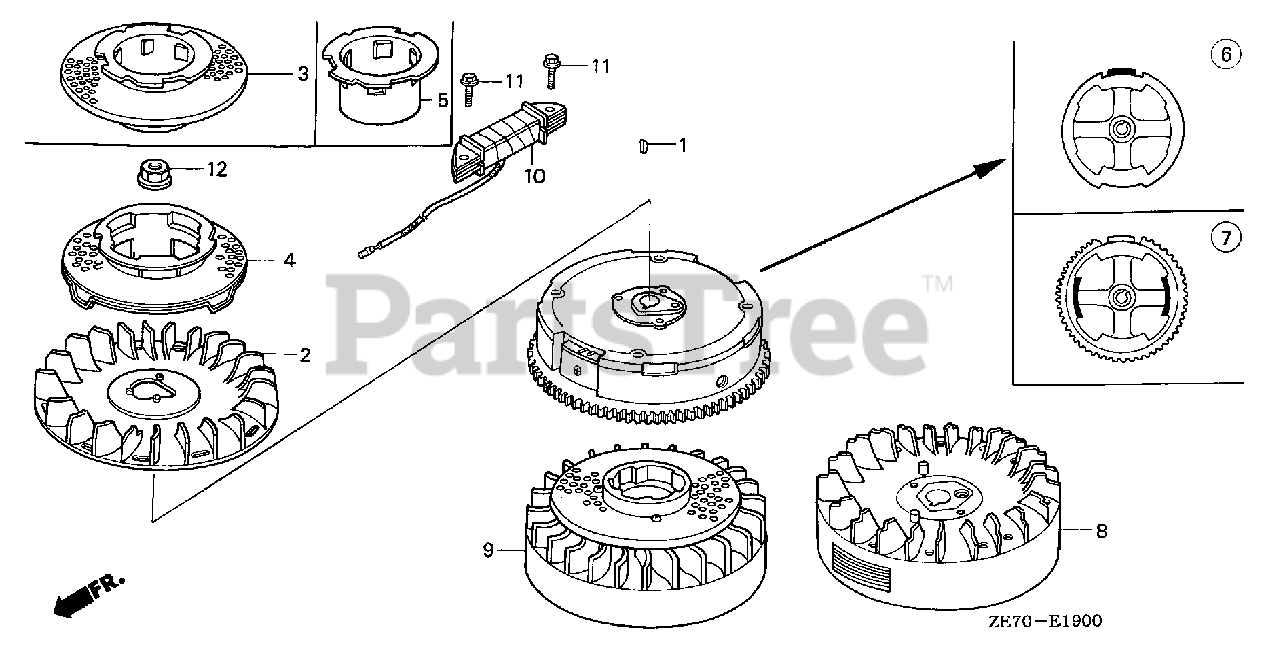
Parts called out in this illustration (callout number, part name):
1	KEY, SPECIAL WOODRUFF (25X18)
2	FAN, COOLING
4	PULLEY, STARTER
7	FLYWHEEL (STARTER MOTOR)
10	COIL ASSY., CHARGE
11	BOLT, FLANGE (6X28) (CT200)
12	NUT, SPECIAL (14MM)
